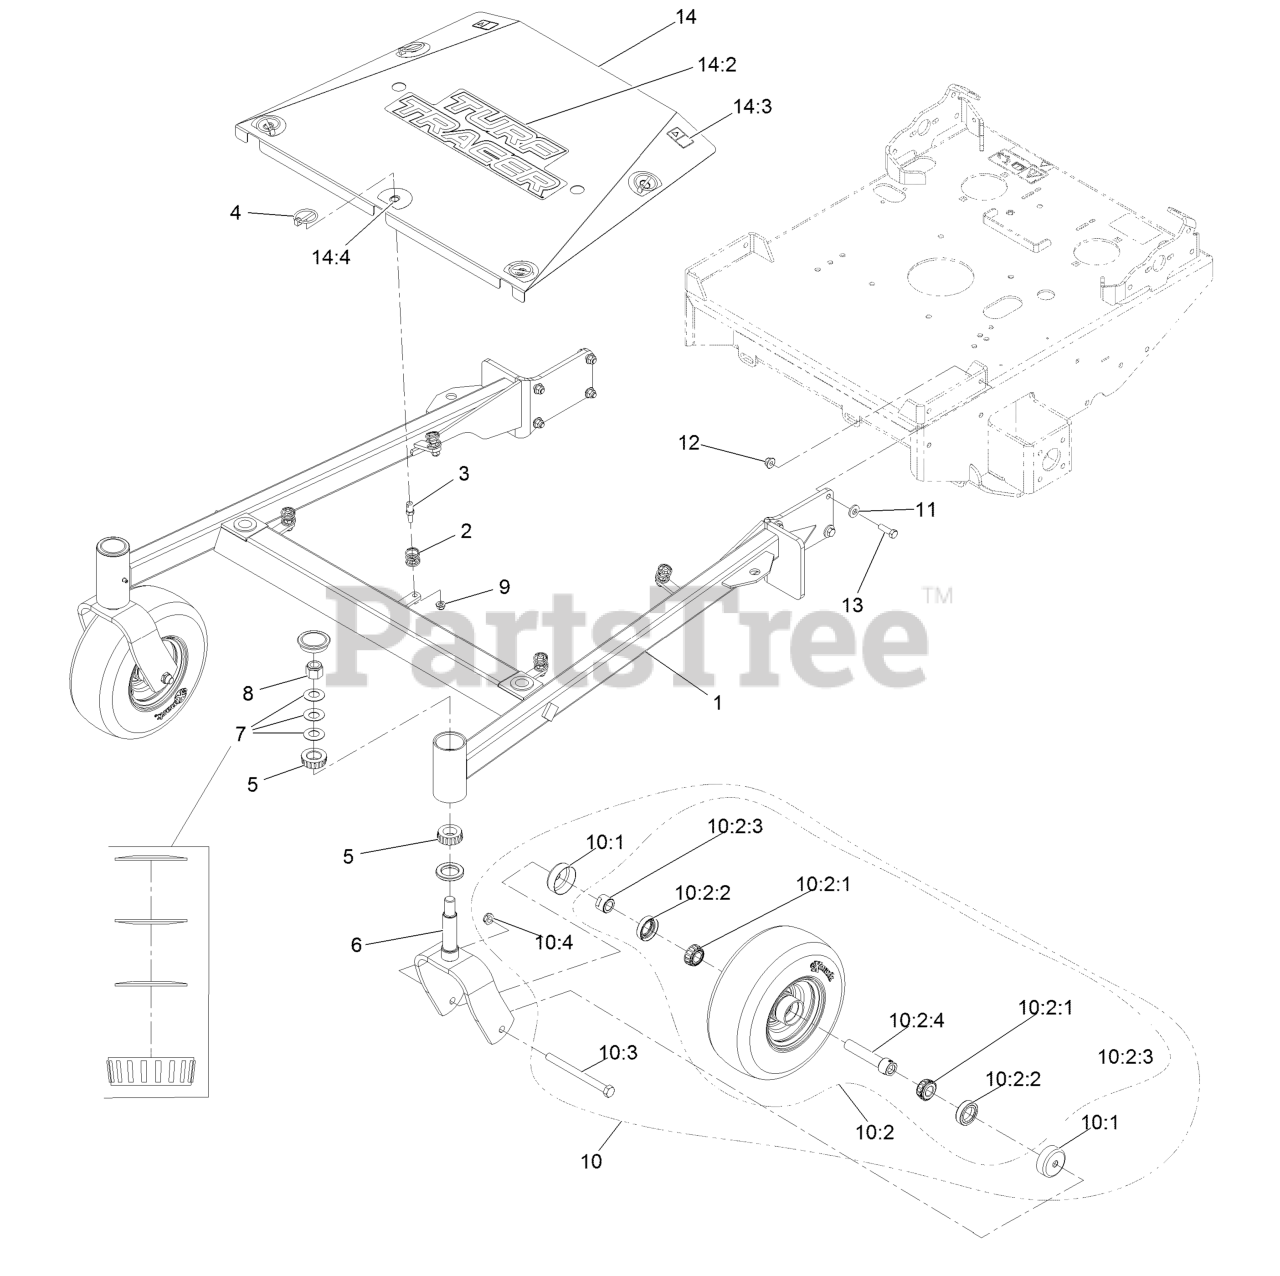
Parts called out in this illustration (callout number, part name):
1	ASM, Front Frame W/Bearings, 52
3	Pin-Spring
4	Pin-Lynch
5	Cone-Bearing Tapered Roller
6	Wld, Caster Fork
7	Washer-Spring Disc
8	Nut-Nyloc 3/4-10
9	Nut-Nyloc 5/16-18 Flg
10	Asm, Wheel And Bearings
10:1	Guard-Seal
10:2	Wheel And Bearing ASM
10:2:1	Bearing-Cone Tapered Roller
10:2:2	Seal-Double Lip
10:2:3	Spacer-Nut
10:2:4	Caster Axle ASM
10:3	Screw-HH 1/2-13 X 6
10:4	Nut-Nyloc 1/2-13 Thin
11	Washer-Spring Disc 3/8
12	Nut-Nyloc 3/8-16 Flg
13	Screw-HH 3/8-16 X 1 1/4
14	ASM, Center Shield W/Decals, 52
14:2	Decal-Turf Tracer
14:3	Decal-Warning
14:4	Decal-Scratch Cover
